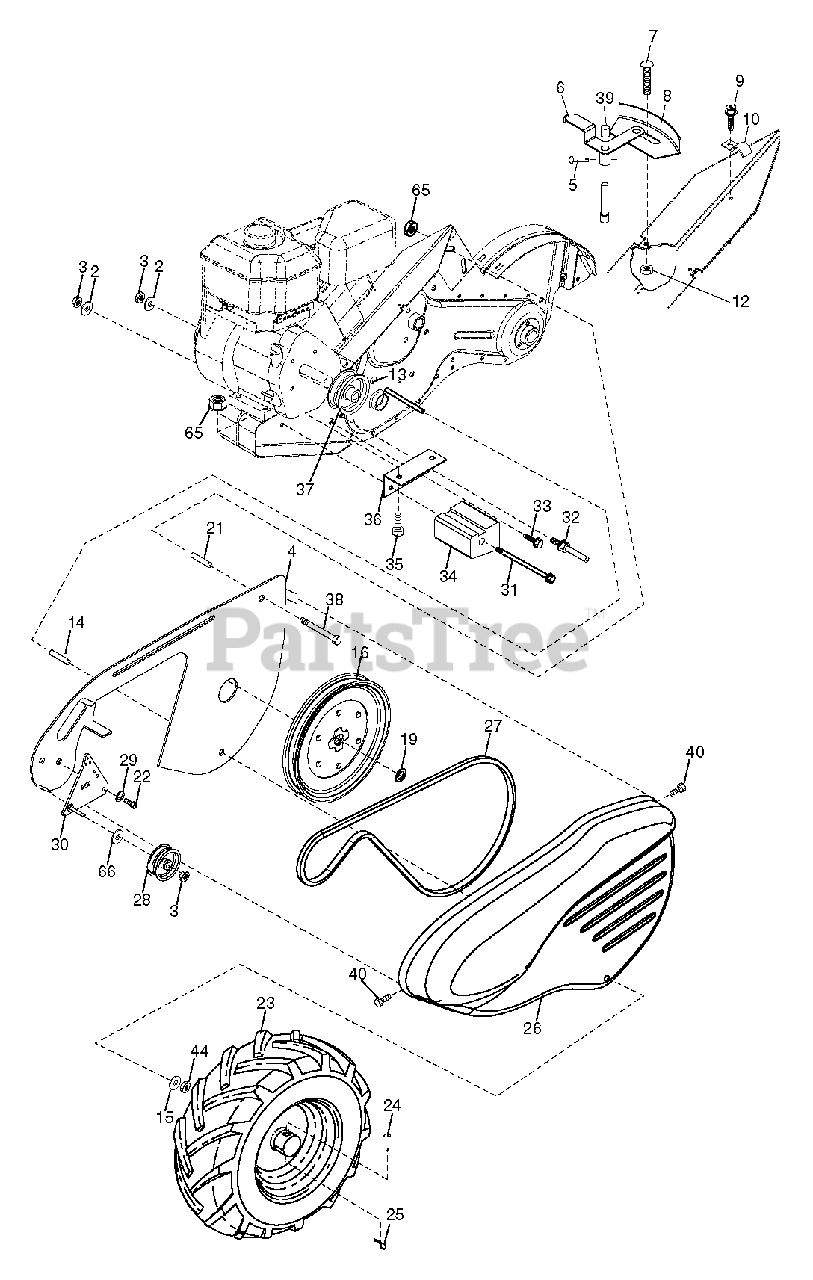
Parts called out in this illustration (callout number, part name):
2	Washer, Lock 3/8
3	Nut, Hex 3/8-16
4	Shield, Inner Belt Guard
5	Pin, Shift Lever
6	Lever, Shift
7	Bolt, Carriage 1/4-20 x 1/2 Gr. 5
8	Plate, Shift Indicator
9	Screw, Hex, Washer Head, Slotted #10-24 x 1/2
10	Clip
12	Nut, Keps Hex 1/4-20 unc
13	Screw, Set, 5/16-18 x 3/8
14	Spacer, Split .327 x .42 x 2.09
15	Washer 11/32 x 11/16 x 16 Ga.
16	Sheave, Transmission
19	Ring, Retainer
21	Spacer, Split .327 x .42 x 1.220
22	Bolt, Fin Hex 5/16-24 x 1/2
23	Tire
23	Tire Valve
24	Rivet, Drilled
25	Retainer Spring
26	Guard, Belt
27	Belt, V
28	Pulley, Idler
29	Ring, Klip
30	Bracket, Idler
31	Bolt, Hex 5/16-16 x 12
32	Shaft, Idler Arm
33	Bolt, Hex 3/8-16 x 1
34	Counterweight, L.H.
35	Bolt Fin Hex 5/16-18 unc x 1-3/4
36	Bracket, Reinforcement, L.H.
37	Sheave, Engine
38	Bolt, Fin Hex 5/16-18 x 2-3/4
39	Cap, Plunger
40	Screw Hex Wsh. Slt #10-24 x .50
44	Nut, Lock 5/16-18
65	Nut, Lock Hex Flange
66	Washer
